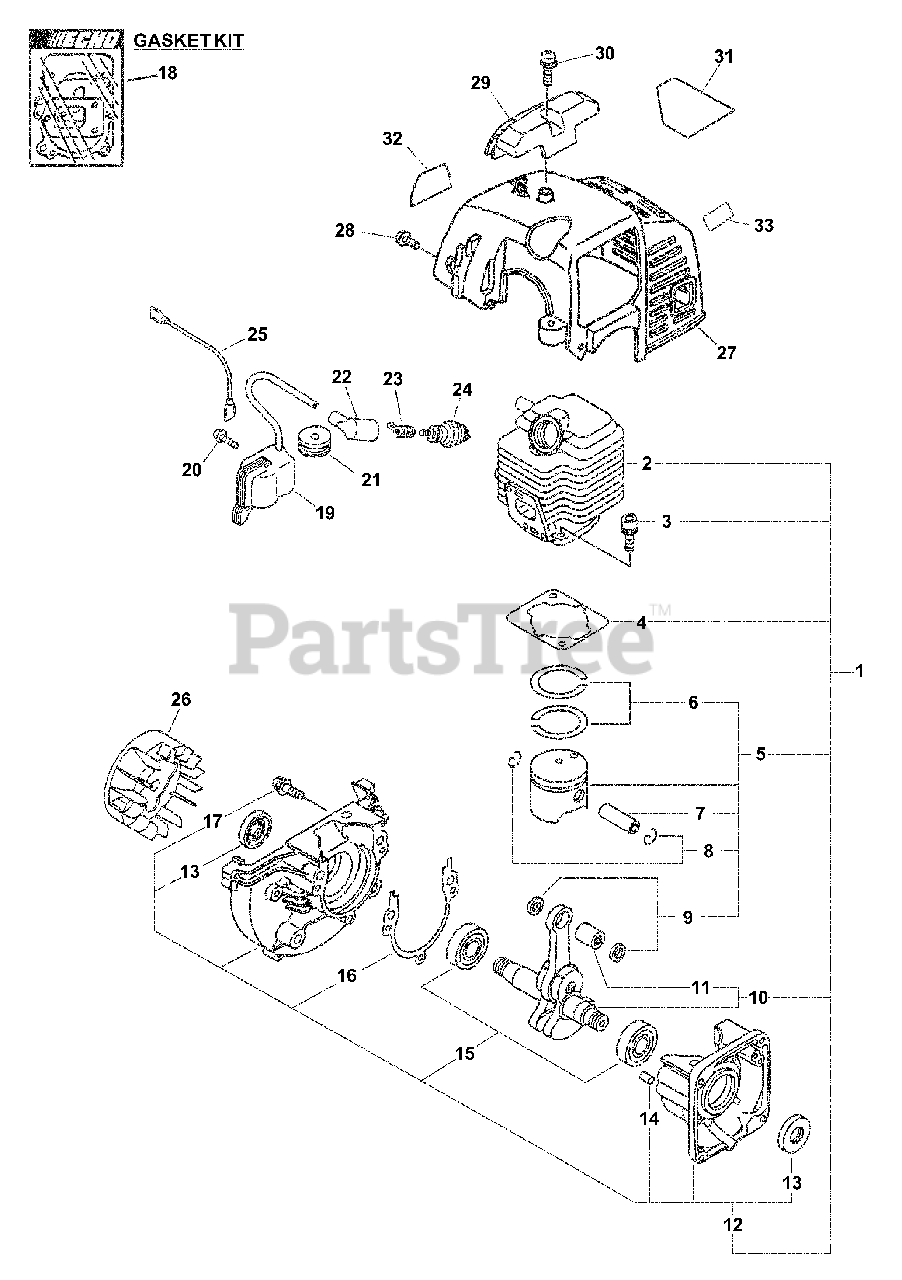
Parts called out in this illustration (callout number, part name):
1	SHORT BLOCK -- SB1048
2	CYLINDER
3	SCREW - 5X22
4	GASKET, CYLINDER
5	PISTON KIT
6	RING, PISTON
7	PIN, PISTON
8	RING, RETAINING
9	SPACER, PISTON
10	CRANKSHAFT ASSY
11	BEARING, NEEDLE
12	CRANKCASE KIT
13	SEAL, OIL
14	PIN - LOCATING
15	BEARING, BALL - 6201
16	GASKET, CRANKCASE
17	SCREW - 5X28
18	GASKET KIT
19	COIL, IGNITION
20	SCREW - 4X22
21	GROMMET
22	CAP, SPARK PLUG
23	TERMINAL, SPARK PLUG CAP
24	SPARK PLUG -- BPM-7A
25	LEAD - IGNITION
26	FLYWHEEL
27	COVER, ENGINE
28	SCREW - 4X12
29	GUARD, TOP - BLACK
30	SCREW - 5X16 -- TAPPING
31	LABEL - CAUTION
32	LABEL - MODEL PPF-211
33	LABEL - HOT SURFACE
